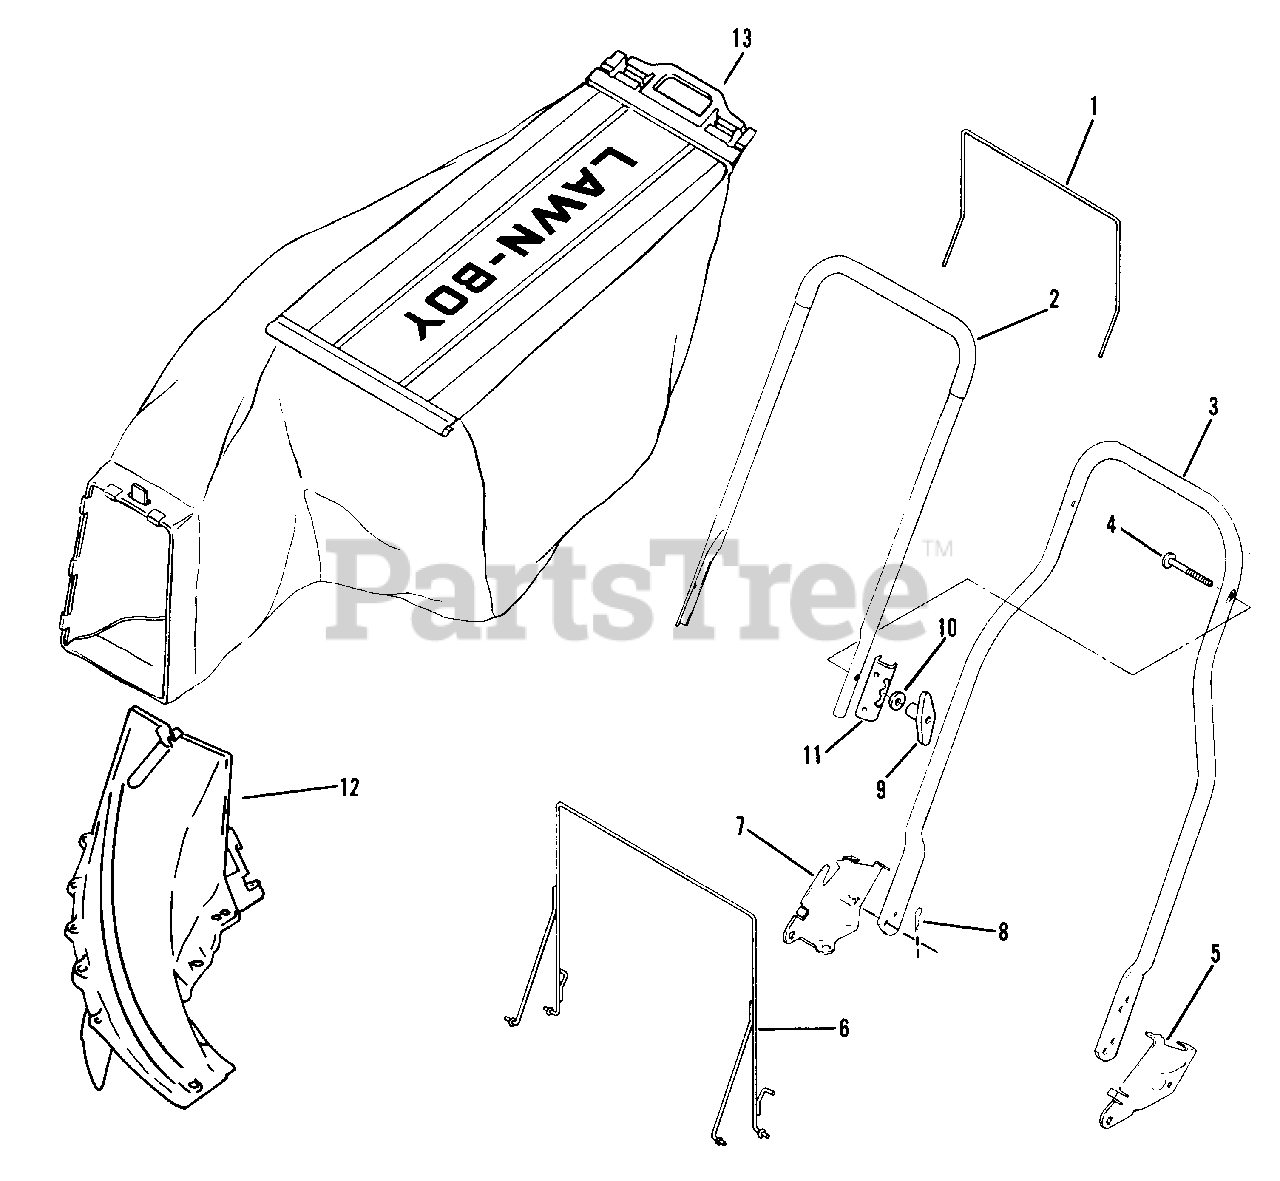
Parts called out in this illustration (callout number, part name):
1	Hanger-Rear
2	Top Handle & Grip Assembly
3	Handle Section-Bottom
4	Screw
5	Handle Bracket-L.H.
6	Hanger Assembly-Front
7	Handle Bracket-R.H.
8	Halr Pin
9	Knob
10	Washer-Curved
11	Bracket-Rear Hanger
12	Chute Assembly
13	Bag & Deflector Assembly
